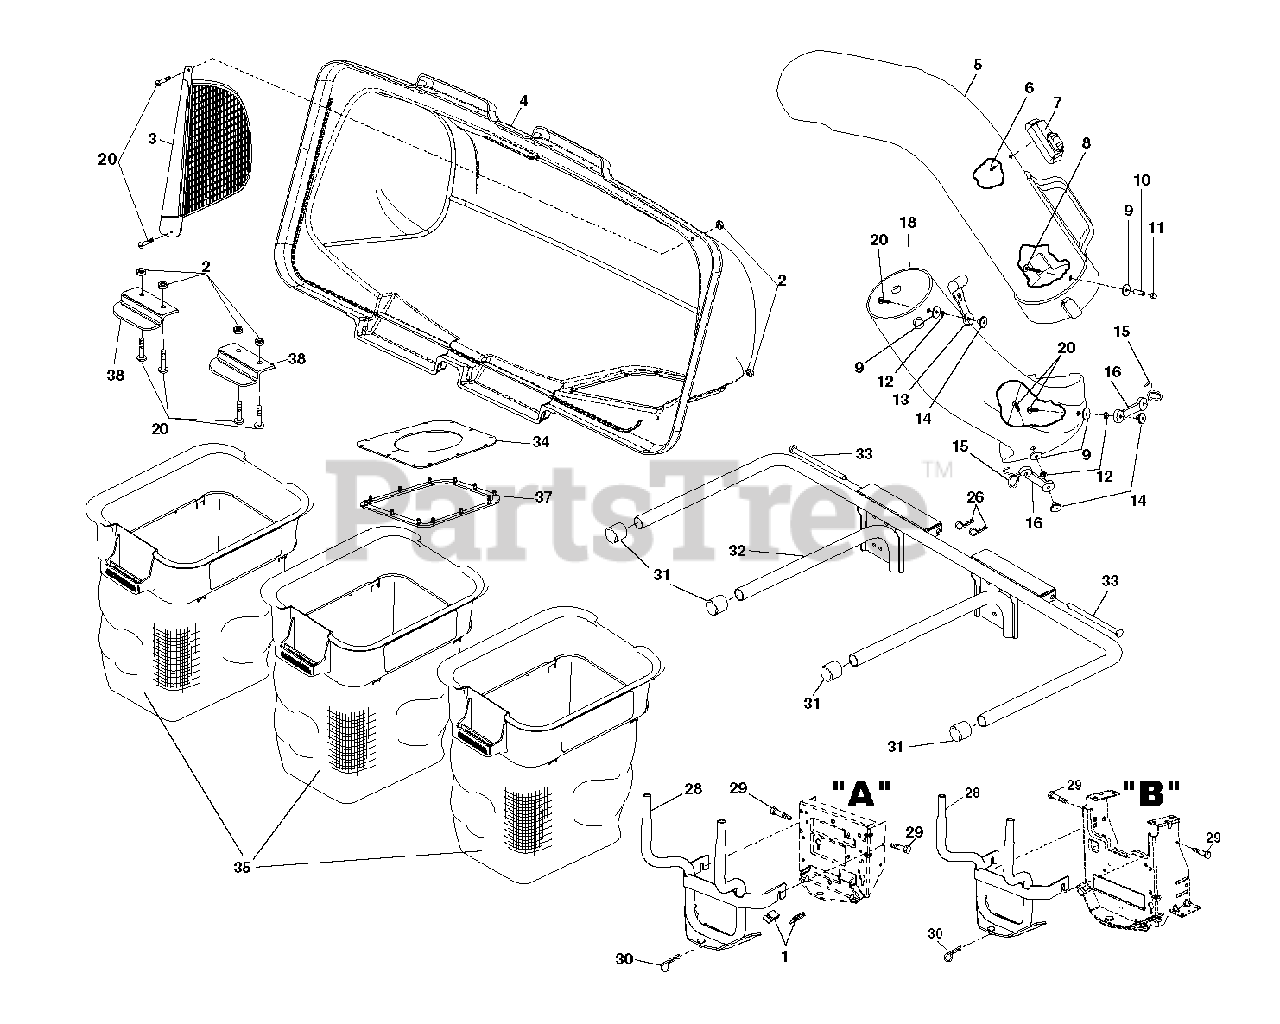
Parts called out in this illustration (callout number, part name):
1	ADAPTER.LT.3-BIN.QA.TEX
3	SCREEN.COVER.BAGGER
4	COVER.ASM.3BIN.GENERIC.
5	CHUTE UPPER
7	INDICATOR ASM BAG
8	SCREW
11	NUT
12	LOCKWASHER (3 2)
13	LATCH.HOOD.
14	WELDNUT
15	HOOK LATCH
16	RUBBER LATCH
18	CHUTE.LOWER.LT.46"
18	CHUTE.BAGGER.LOWER.48"
20	SCREW
26	Retainer Spring
28	BRACKET.BAGGER.3-BIN.BLACK
29	SHOULDER BOLT, SELF-TAP
30	SPRING.RETAINER.YELLOW.ZINC
31	PLUG, TUBING END
32	BAGGER.ASM.FRAME.3BIN.BLACK
33	BAGGER.HINGE.PIN
34	SEAL.BAGGER.TOP.3-BIN.BLK
35	CONTAINER BAG, SOFT
37	GASKET.COVER.BAGGER
38	LATCH CER38
